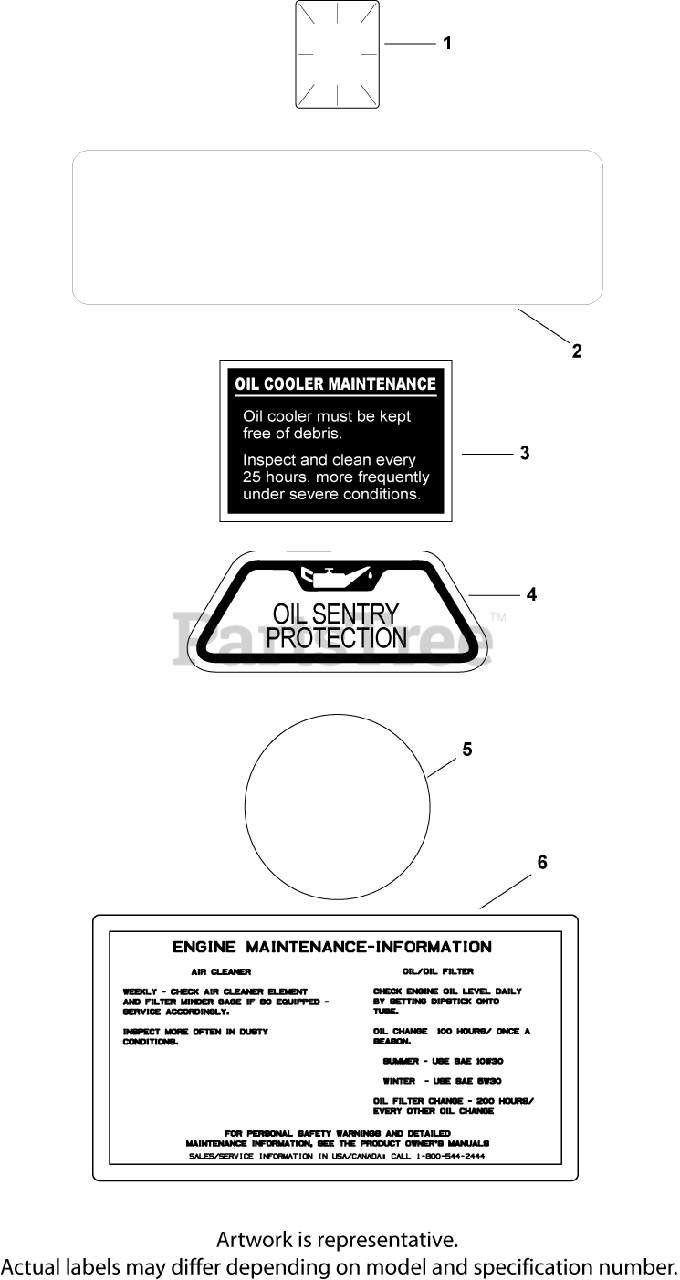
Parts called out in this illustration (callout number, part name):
1	DECAL, CLEAR LAMINATE USE 25 113 70-S
2	DECAL, 27 HP
3	DECAL, OIL COOLER - (#DSC)
4	DECAL, OIL SENTRY - (#DSC)
5	LABEL, (ROUND KOHLER GOLD)-USE 24 113 18
6	DECAL, AIR CLEANER - (#DSC)
